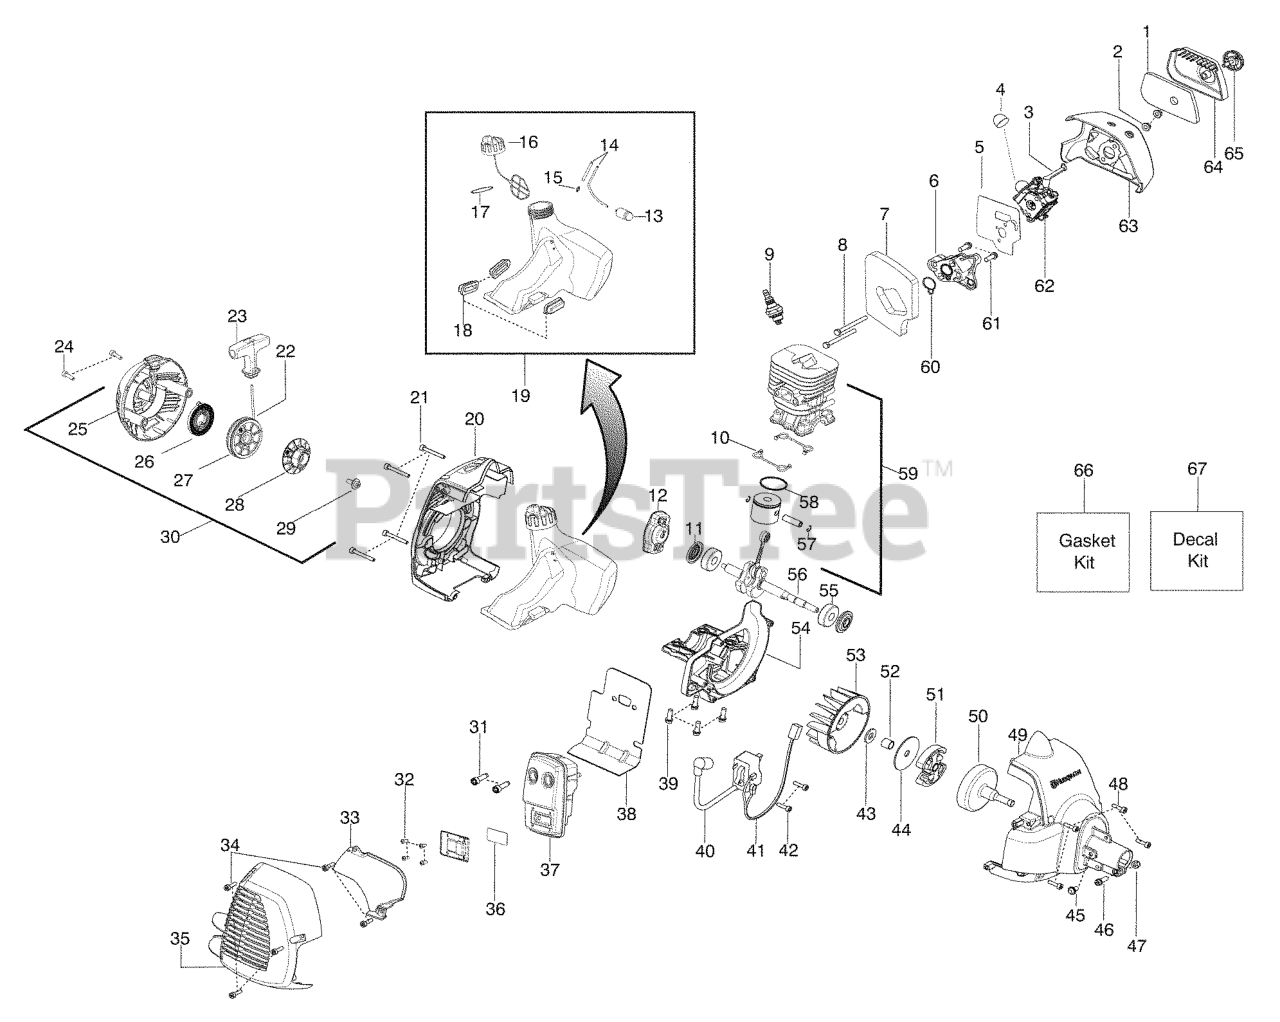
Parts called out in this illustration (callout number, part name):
1	FILTER AIRBOX
3	CHOKE LEVER
4	PURGE BULB ZAMA
5	KIT GASKET CARB 28CC
6	CARB ADAPTOR
7	KIT GASKET 28CC
8	BOLT CARB ADAPTOR
9	Plug-Spark (RCJ-6Y)
10	KIT GASKET 28CC
11	KIT GASKET 28CC
12	STARTER PAWL BRIDGE
13	FUEL PICK-UP ASSY
14	KIT-LINE(FUEL)
15	FUEL LINE FITTING
16	ASSY-CAP W/RETAINER
17	KIT GASKET 28CC
18	ISOLATOR FUEL TANK
19	KIT FUEL TANK HVA
20	REAR SHROUD
22	KIT ROPE
23	STARTER HANDLE
24	SCREW M5-0.8X30MM
25	HSG STARTER W/EYELET
26	KIT STARTER SPRING
27	KIT STARTER PULLEY
28	DRIVER PULLEY
30	ASSY STARTER HSG
31	BOLT MUFFLER
32	SCREW-6-19X5/16PLAST PA
33	SHIELD HEAT
34	SCREW M4 X 1.75 PT 16MM
35	GUARD-MUFFLER
36	KIT SPARK ARRESTOR SCREEN
37	ASSY-MUFFLER
38	KIT GASKET 28CC
39	SCREW-M5-0.8 X 25MM(TAP)
40	IGNITION MODULE MB45
41	ASSY MODULE LEAD WIRE
42	SCREW M4 X .70 TT 16MM
43	WASHER CLUTCH
44	WASHER-CLUTCH
47	LOCKNUT-HEX 10-24
48	SCREW M4 X .70 TT 16MM
49	FAN HSG ASSY
50	ASSY-CLUTCH DRUM
51	%KIT CLUTCH ASSY
52	SPACER FLYWHEEL
54	CRANKCASE CAST LE28
55	BEARING RADIAL BALL (6201)
56	ASSY CRANKSHAFT
57	WRIST PIN RET.
58	RING PISTON
59	KIT PISTON & CYLINDER
60	KIT GASKET 28CC
61	SCREW-M5-0.8 X 25MM(TAP)
62	CARBURETOR KIT W38
63	RP_AIR BOX
64	COVER-AIR BOX
65	KNOB ASSY AIRBOX COVER
66	KIT GASKET 28CC
